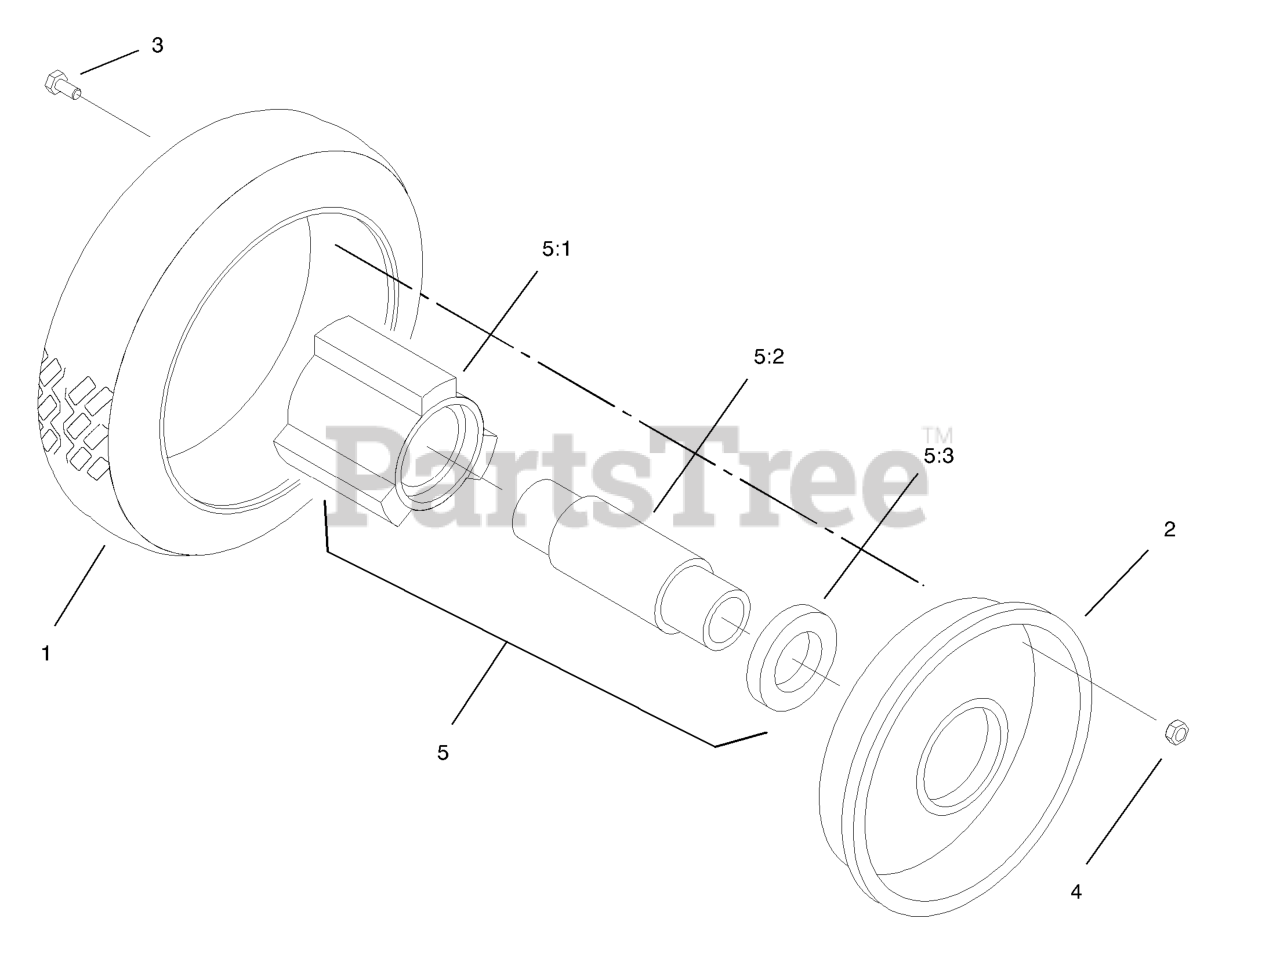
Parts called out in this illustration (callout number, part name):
3	SCREW-HH
4	NUT-LOCK, NI
5	Hub & Bearing Asm
5:1	HUB-BEARING
5:2	SPACER-BEARING
5:3	BEARING-WHEEL
